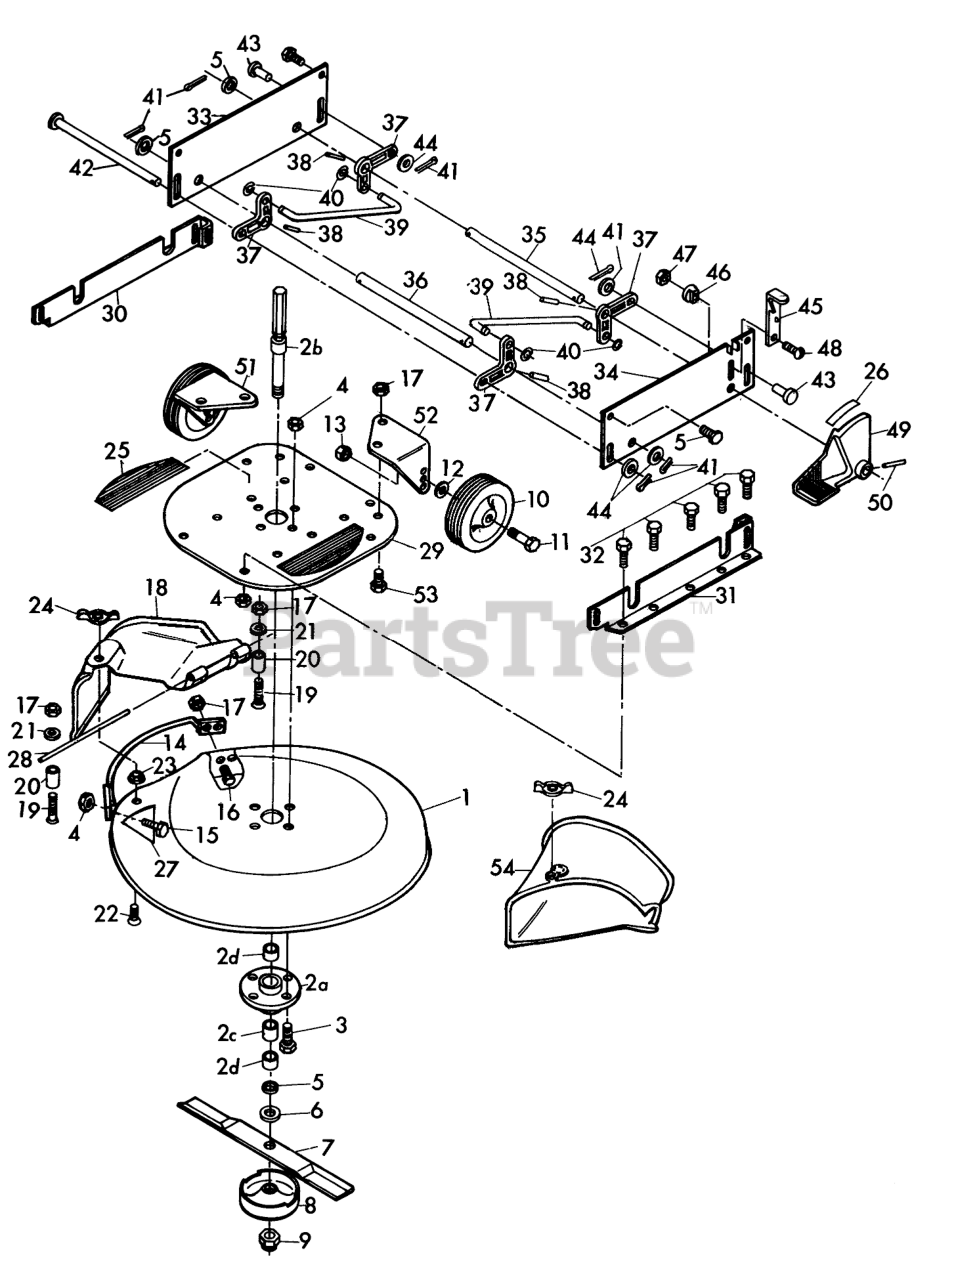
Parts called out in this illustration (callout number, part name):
1	Mower Housing
2	Spindle Housing Consists of:
3	SCREW-HH
5	WASHER
6	WASHER
7	Blade
8	Cup
9	Nut
10	Wheel
12	WASHER-FLAT
13	Nut
15	5/16-18X5/8 TRS HD MS
17	Nut
18	DEFLECTOR
19	Screw
20	Spacer
21	WASHER-FLAT
22	5/16-18X7/8 FLT HD MS
23	PAL NUT
24	Wing Nut
25	Footpad
26	Cutting Height Decal
27	Safety Decal
28	Hinge Pin
29	Shroud
30	Mounting Bracket (R.H. lower)
31	Mounting Bracket (L.H. lower)
32	SCREW-HH
33	Mounting Plate R.H.
34	Mounting Plate L.H.
35	Rear Pivot Shaft
36	Front Pivot Shaft
37	Bell Crank
38	Roll Pin
39	Lift Link
40	RING-RETAINING, EXT
41	PIN-COTTER
42	Lift Shaft
43	Lift Pin
44	Washer
45	Lift Pawl
46	Pawl Slide Nut
47	NUT-HEX
49	Lift Ratchet
50	Roll Pin
51	Wheel Bracket R.H.
52	Wheel Bracket L.H.
53	SCREW-HH
54	Bagging Attachment Adapter Not Included With Tractor
